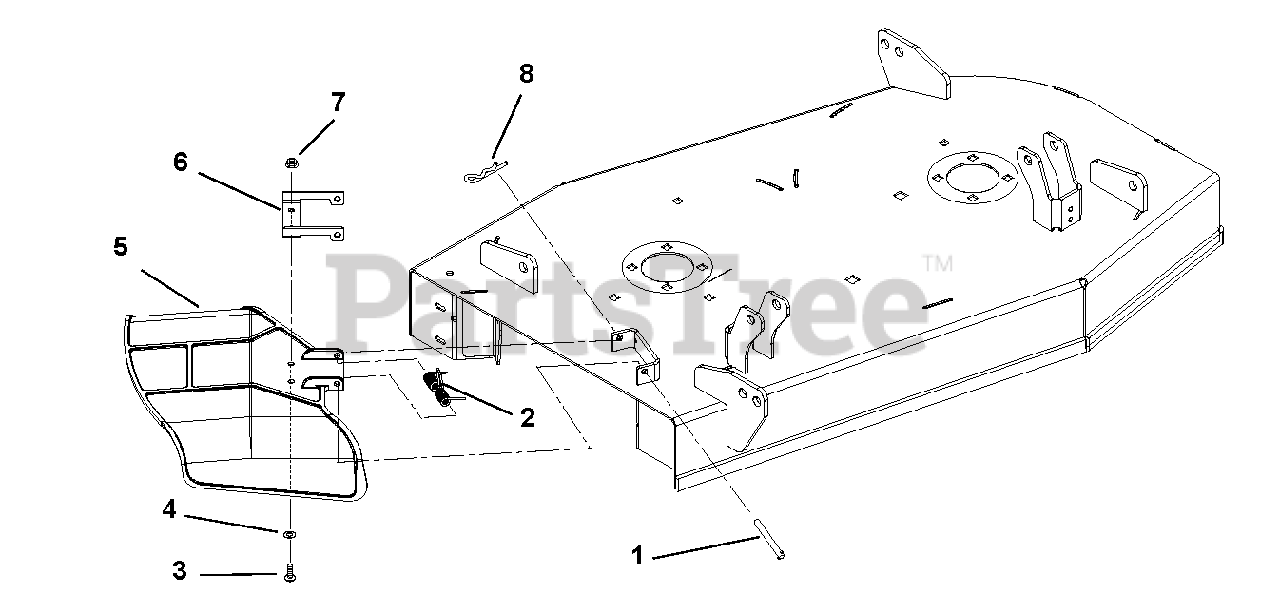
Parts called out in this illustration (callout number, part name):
1	Clevis Pin
2	Spring, Torsion
3	Screw, Socket Head, Button Head .31-18 x .75
4	Washer, Flat Steel .38 x .875 x .083
5	Plastic Chute
6	Chute Reinforcement
7	Nut, Locking, Top Flange .31-18
8	Pin, Hair .08 x .18 x 1.1
